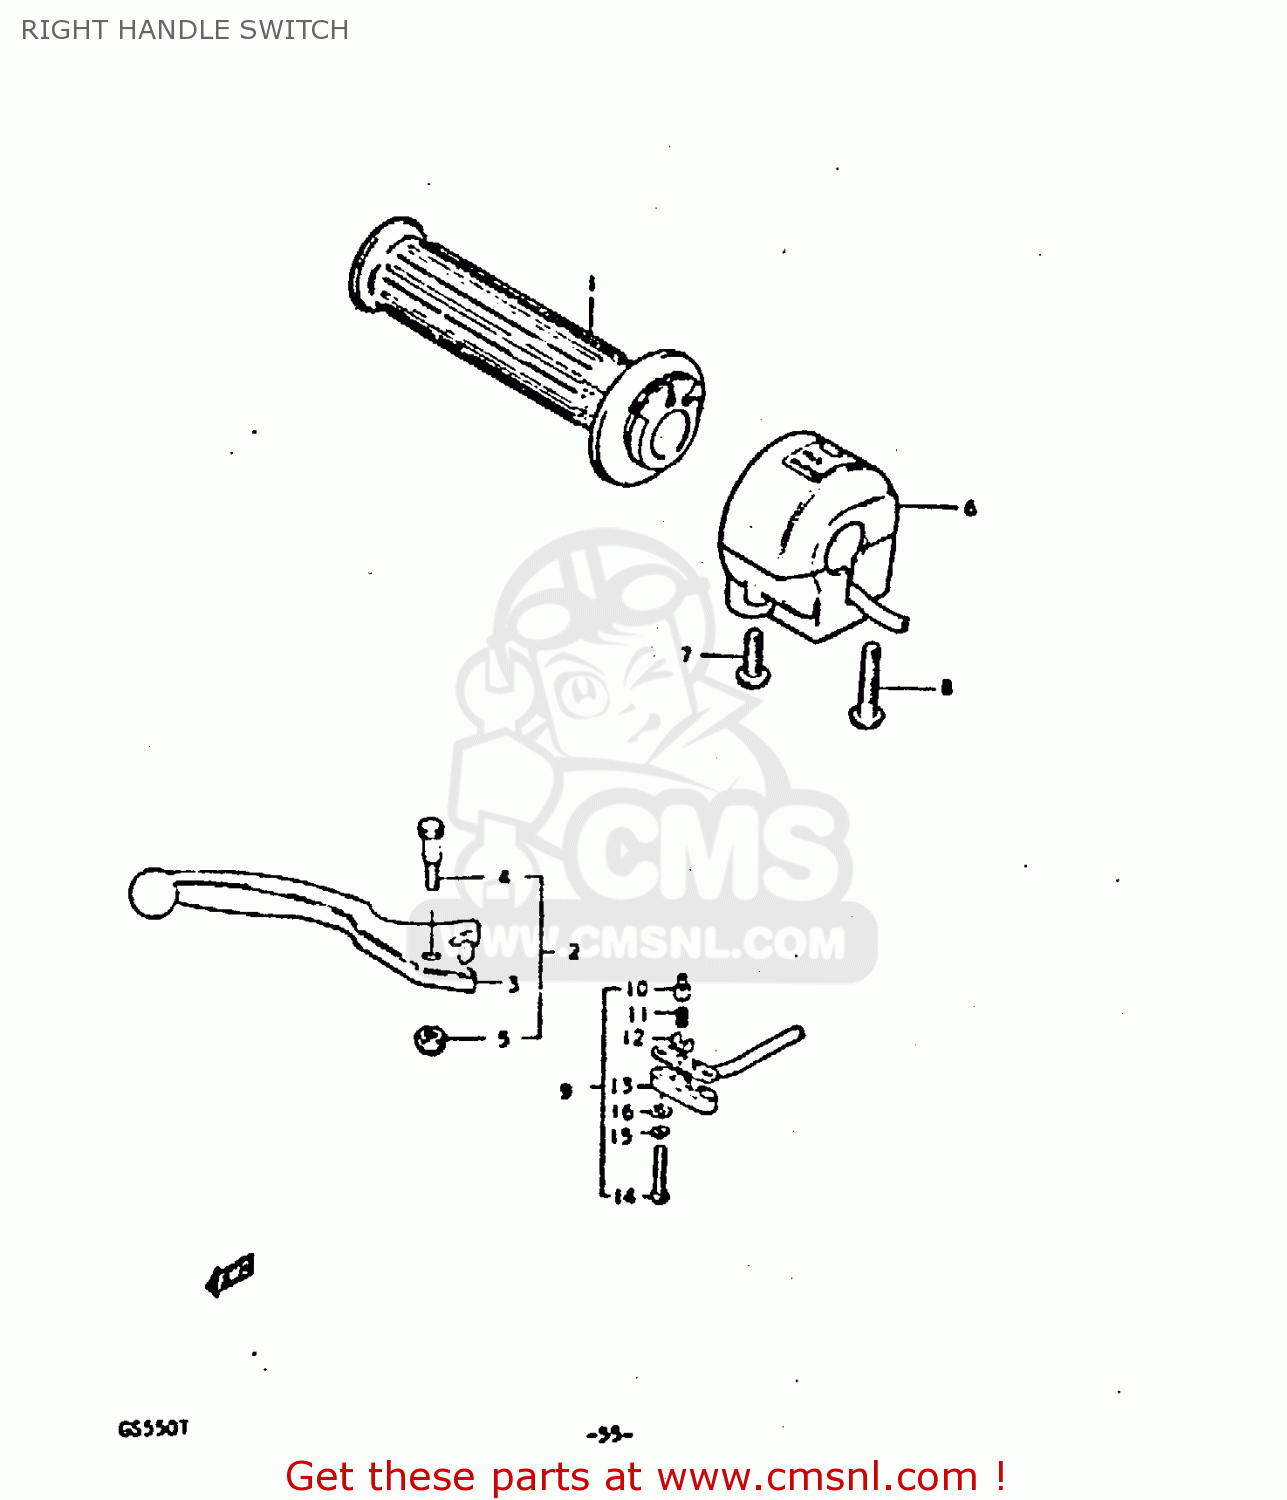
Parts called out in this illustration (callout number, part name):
1	GRIP,THROTTLE
2	LEVER ASSEMBLY,BRAKE
3	LEVER,BRAKE
4	BOLT
5	NUT 6MM
6	SWITCH ASSEMBLY,HANDLE,RIGHT
7	SCREW
8	SCREW
